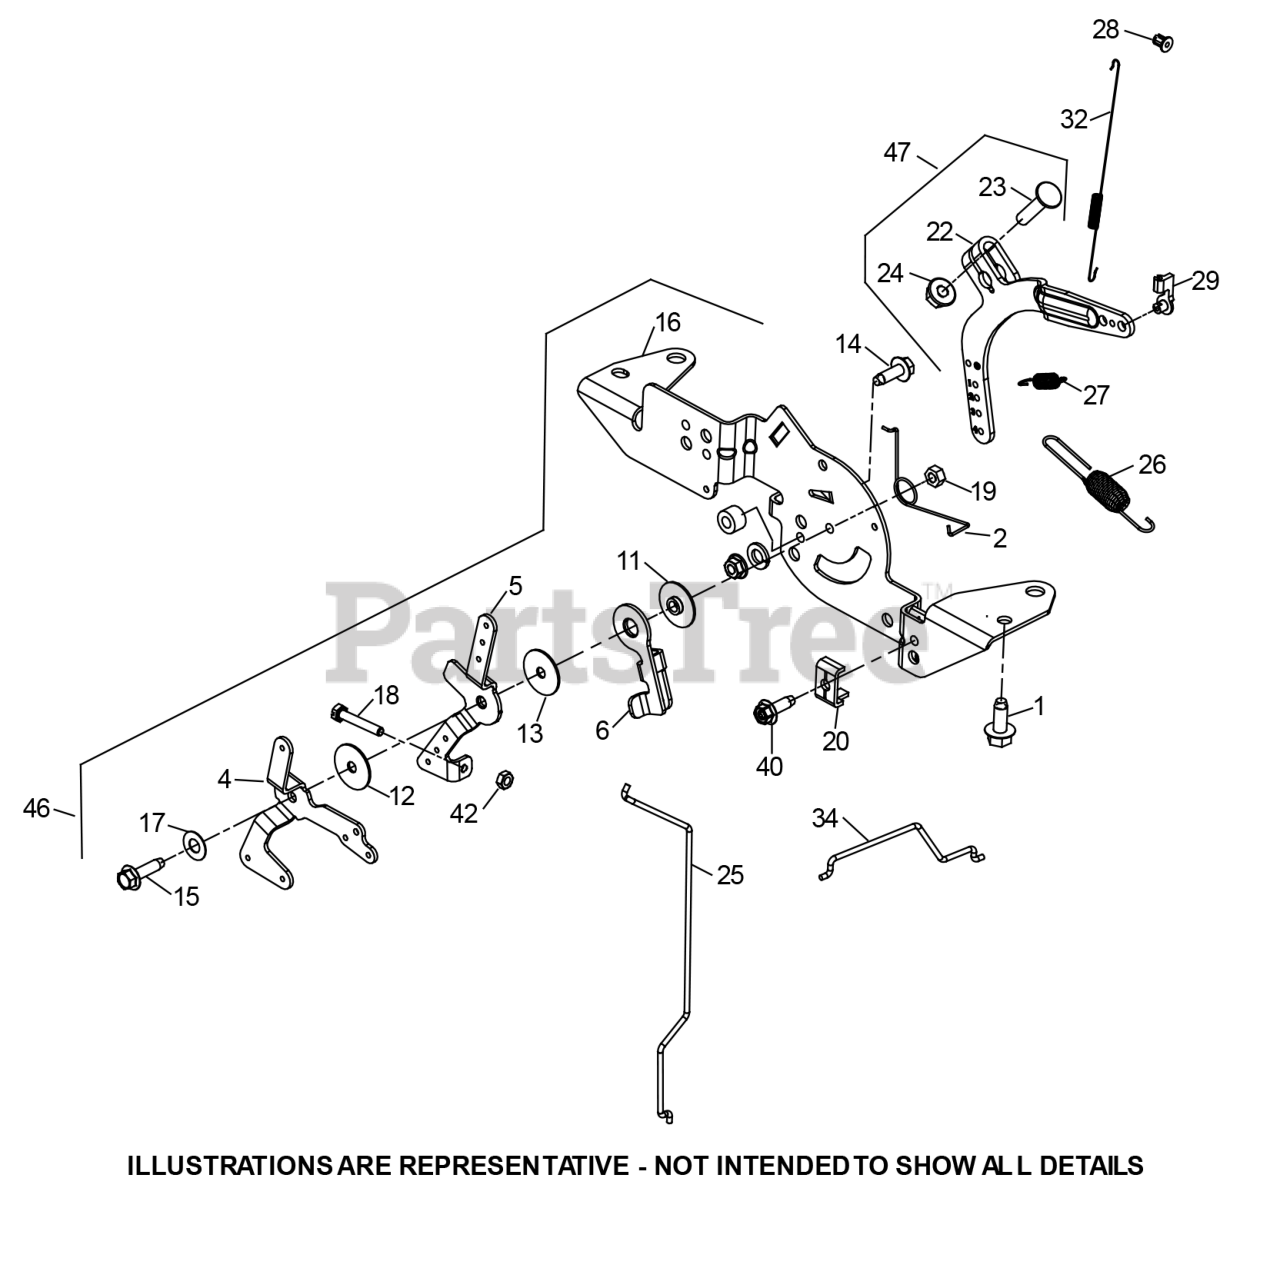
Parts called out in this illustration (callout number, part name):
1	SCREW-THREAD FORMI
2	SPRING-CHOKE RETRN
5	LEVER-THROTTLE CON
6	LEVER-THROTTLE ACT
11	SPACER-CONTROL ASSEMBLY
15	THREAD FORMING SCREW
16	SPEED CONTROL BRACKET
22	LEVER-GOVERNOR ASSEMBLY
23	BOLT-RD HD SQ NECK
24	HEX FLANGE NUT
25	CHOKE LINKAGE
26	GOVERNOR SPRING
27	GOVERNOR SPRING
29	BUSHING-RETAINING
32	LINKAGE SPRING
34	THROTTLE LINKAGE
40	THREAD FORMING SCREW
46	SPEED CONTROL ASSEMBLY
47	LEVER-GOVERNOR ASSEMBLY
